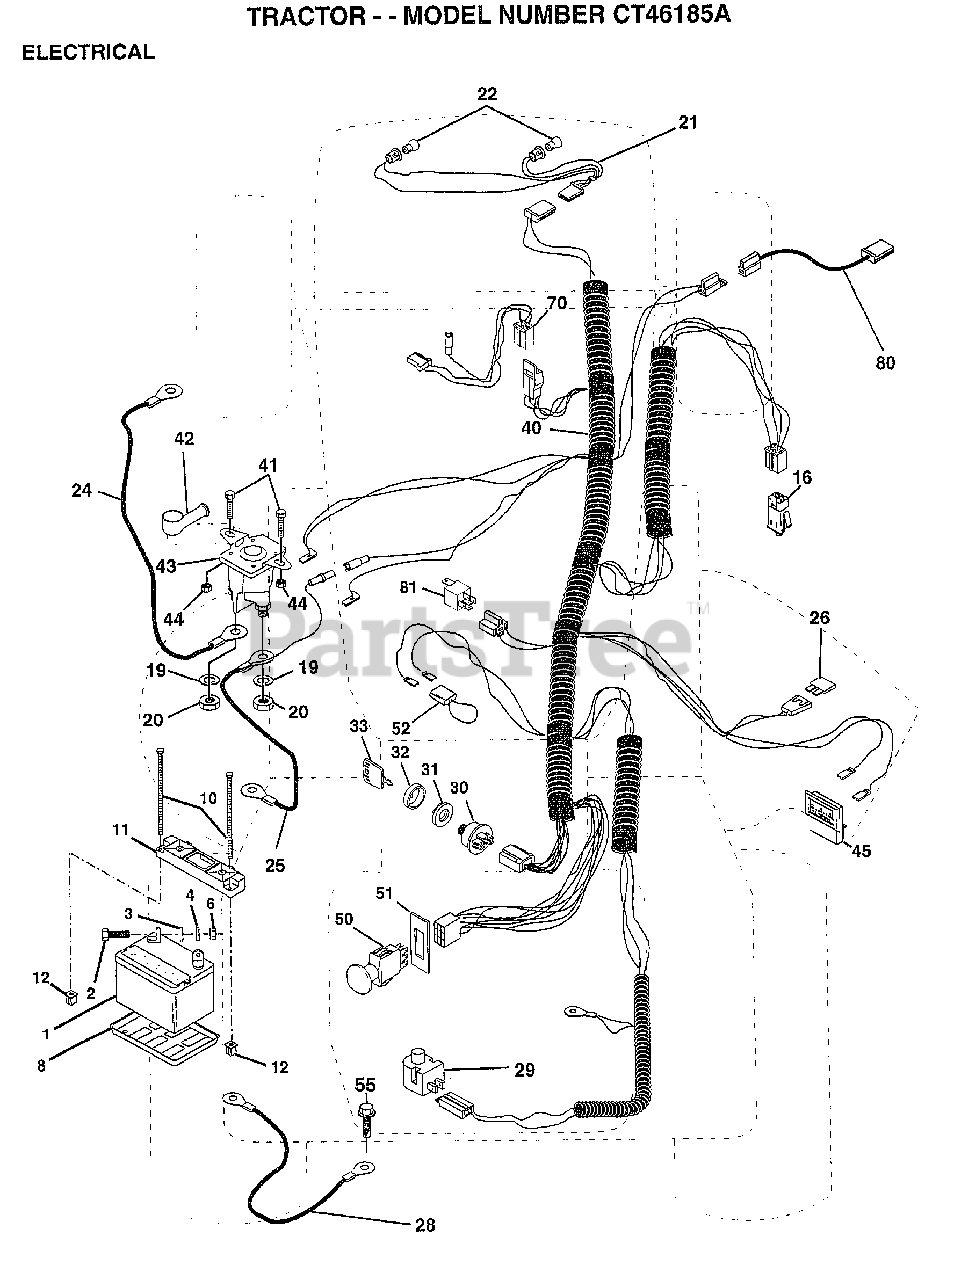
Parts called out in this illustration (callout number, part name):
2	BOLT LT
3	WASHER
4	LOCKWASHER
8	"TRAY T, BATTERY"
11	HOLDDOWN BATTERY
16	SWITCH INTERLOCK
20	NUT
21	"HARNESS,LIGHT SOC"
22	HEADLAMP BULB
24	"CABLE T, BATTERY"
25	CABLE.6GA.22W/16W
26	FUSE HYT
28	CABLE.GRND.6GA.21
29	SWITCH.PLUNGER
30	SWITCH IGN 4POS
31	NUT IGNITION
32	COVER KEY SWITCH
33	KEY
40	"HARNESS.IGN.AM,HM"
41	BOLT HXHD FIN
44	NUT HXKEP 1/4X20
50	PTO SWITCH.BLK
51	RING RETAIN PTO
52	PROTECTION LOOP
55	SCREW LT
70	HARNESS ENG DUAL
80	HARNESS.CLUT.EVX.
81	RELAY ASSY T
